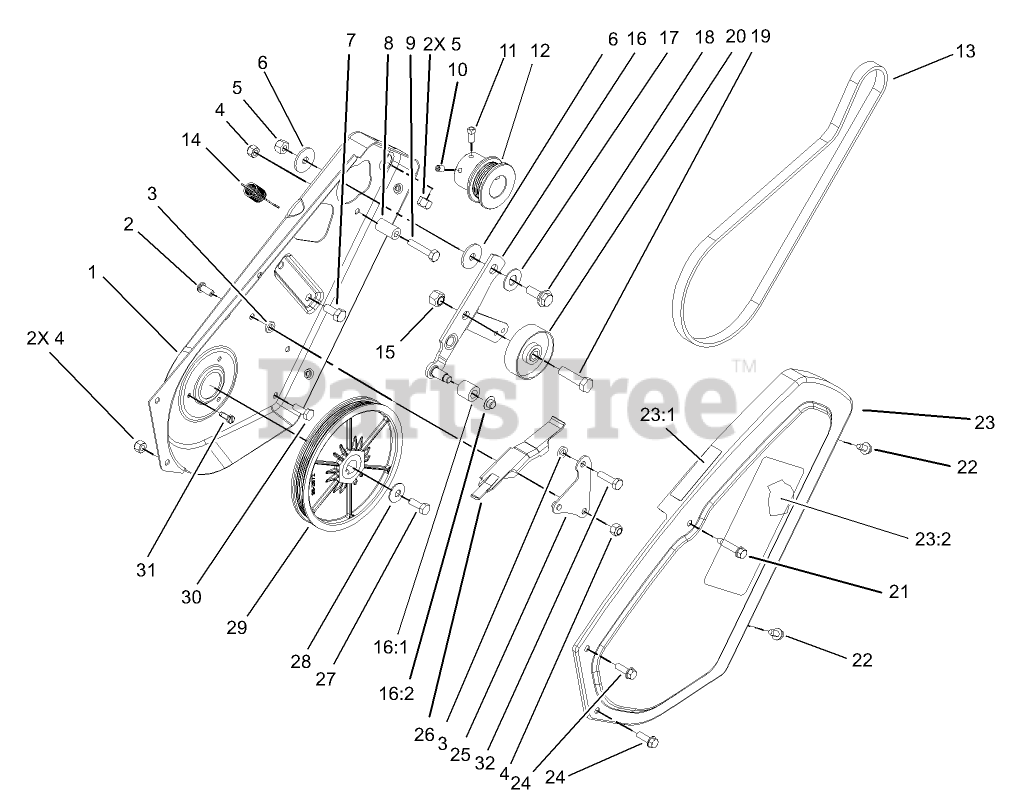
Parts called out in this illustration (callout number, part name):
1	PLATE-SIDE, LH
2	SCREW-HSBH
3	SPACER-PLATE, PIVOT
4	NUT-LOCK, NI
5	NUT-LOCK, NI
6	WASHER-PIVOT
7	SCREW-HH
8	SLEEVE-GUIDE, BELT
9	SCREW-HH
10	SCREW-HSH
11	SCREW-SQH
12	PULLEY-ENGINE
13	BELT-DRIVE
14	SPRING-EXTENSION
15	NUT-LOCK, CONE
16	IDLER ARM ASM
16:1	ROLLER-BRAKE
16:2	NUT-PUSH
17	WASHER
18	SCREW-SHOULDER
19	SCREW-HH
20	PULLEY-IDLER
21	SCREW-HWH, TAP
22	SCREW
23	COVER-DRIVE
23:1	DECAL-WARNING
23:2	DECAL
24	SCREW-HWH
25	PIVOT PLATE ASM
26	BRAKE-ARM
27	SCREW-HH
28	WASHER-BELLEVILLE
29	PULLEY ROTOR ASM
30	SCREW-HH
31	SCREW-SHH
32	SCREW-HH
